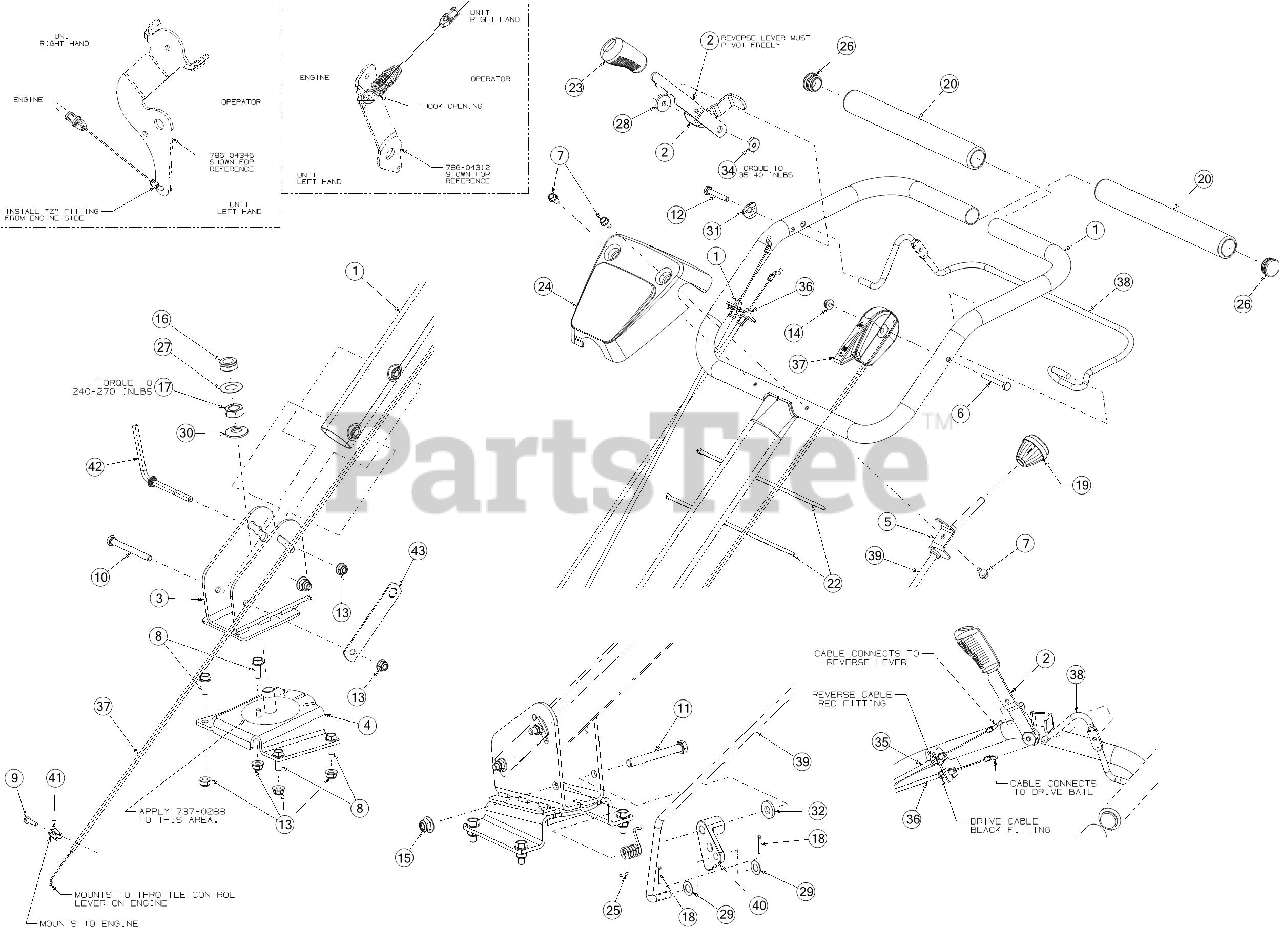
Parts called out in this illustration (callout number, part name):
1	UPPER HANDLE ASSEMBLY
2	REVERSE HANDLE ASSEMBLY
3	PIVOT BRACKET ASSEMBLY
4	BRACKET ASSEMBLY
4	SCREW 1/4-20X.75 GR5
5	PIVOT ROD BRACKET
5	ROD CONTROL BUSHING
6	SCREW 1/4-20 x 2 GR5
7	SCREW 1/4-20 X.500
8	SCREW 5/16-18 x .875 GR5
9	SCREW #10-32 x .75
10	SCREW 5/16-18 x 3.25 GR5
11	SCREW 3/8-16 x 3.25 GR8
12	BOLT 1/4-20X1.62 GR5
13	FLANGE LOCK NUT 5/16-18
14	FLANGE LOCK NUT
16	HEX NUT
17	HEX JAM NUT 5/8-18
18	COTTER PIN 3/32
19	SHIFT KNOB
20	FOAM GRIP .970 x 11.0
23	BRAKE HANDLE GRIP
24	HANDLE COVER W/O SWITCH HOLE
25	HANDLE ADJUSTMENT SPRING
27	FLAT WASHER
28	FLAT WASHER
29	WASHER THRUST .375X.70X.030
30	BELL WASHER
31	SADDLE WASHER
32	FLAT WASHER
33	GREASE
34	SHOULDER SPACER
35	REVERSE CABLE
36	FORWARD CABLE
37	THROTTLE CABLE ASSEMBLY
39	PIVOT CONTROL ROD
40	HANDLE SWING LINK
41	CASING CLAMP
42	CRANK ADJUST HANDLE
43	RETURN BRACKET
